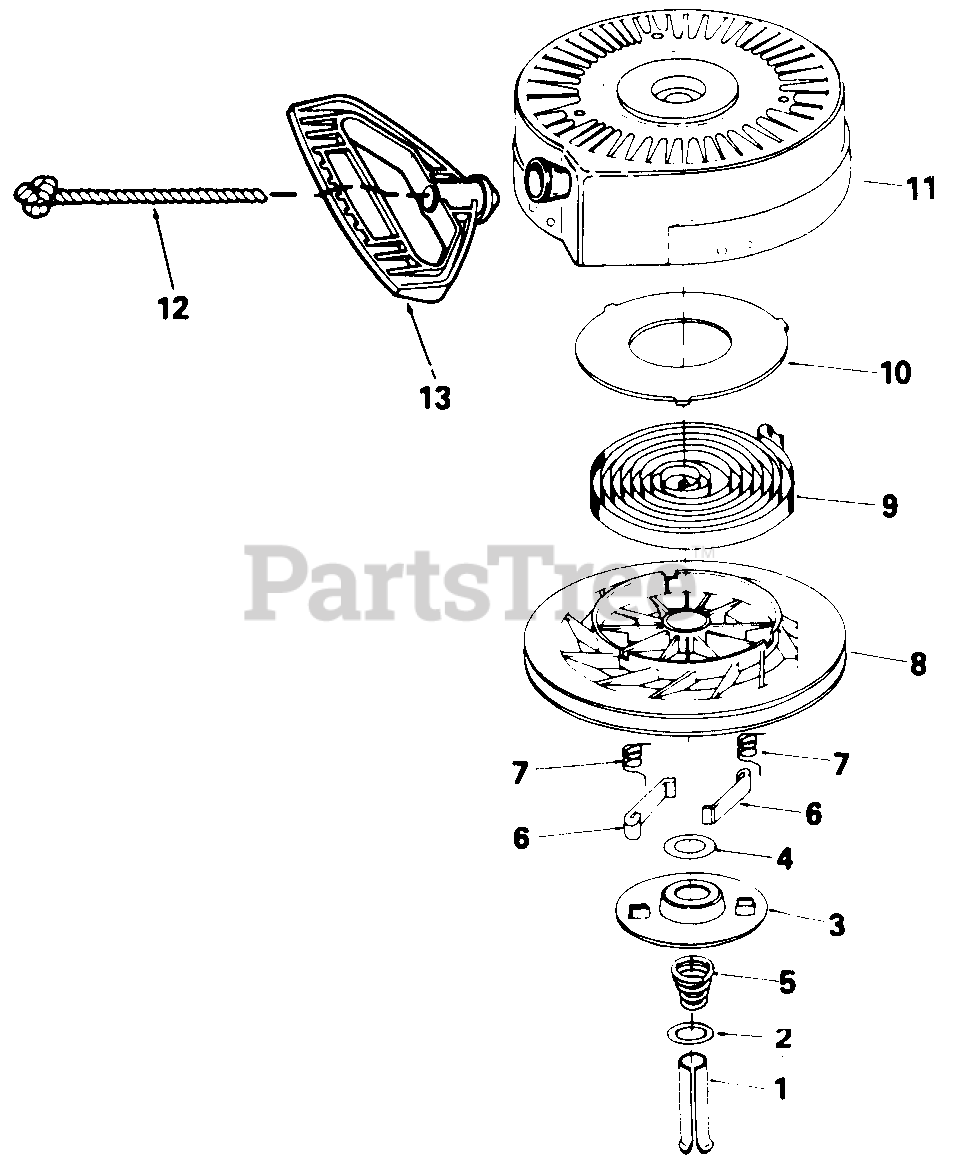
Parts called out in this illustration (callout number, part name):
1	Pin, Spring
4	Washer
5	Spring, Brake
6	Dog, Starter
7	Spring, Dog
8	Pulley
9	Spring, Rewind
10	Cover, Spring
11	Housing Ass'y., Starter
12	Rope, Starter (Length 98" & 9/64" Dia.)
13	Handle, Mitten Grip
